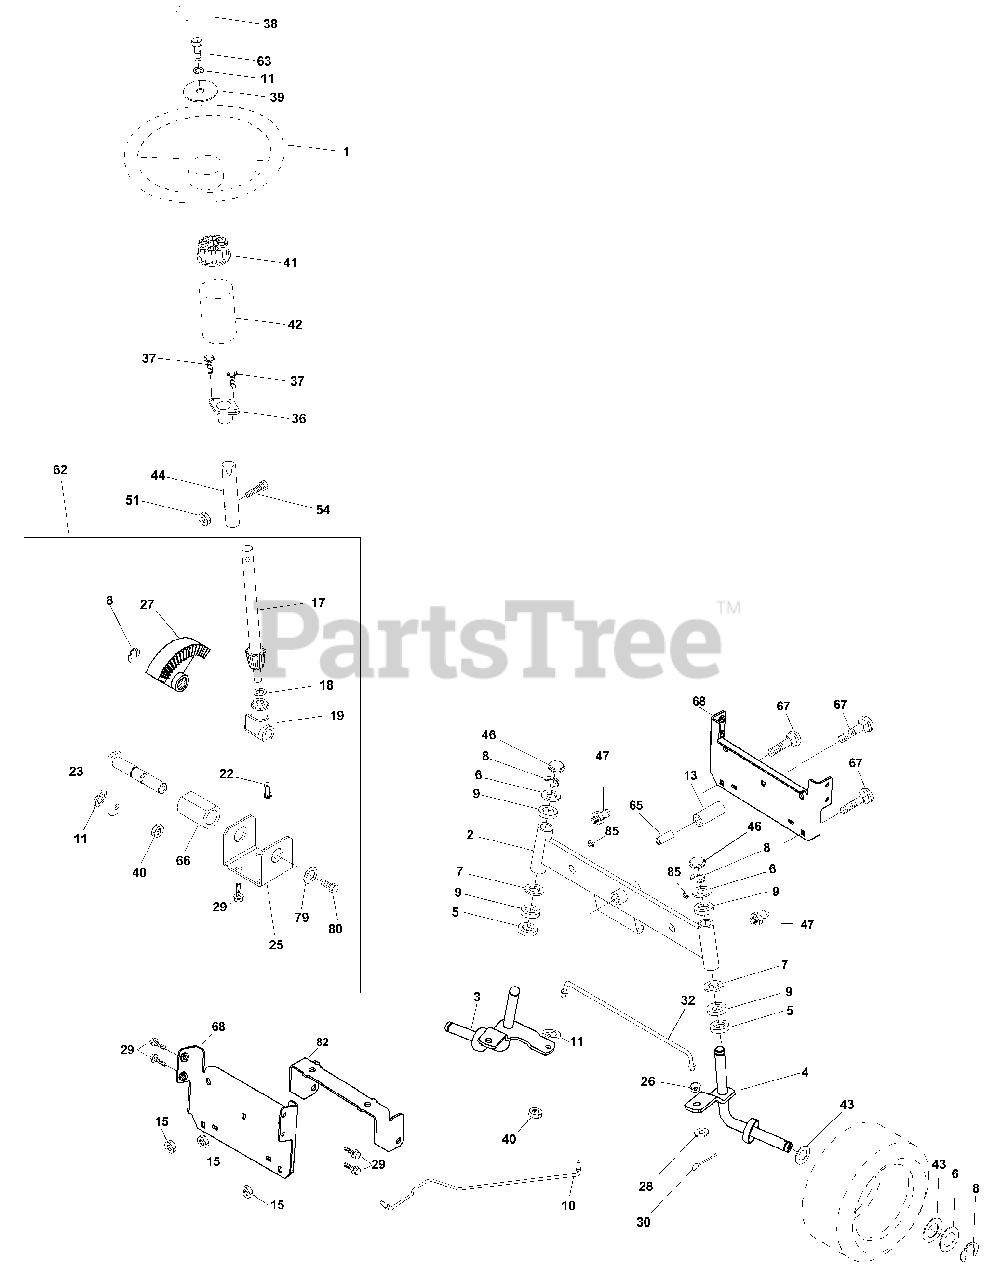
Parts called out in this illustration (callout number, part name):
1	Wheel Steering Ayp/P/L Blk
2	Axle Asm
3	Spindle Asm LH
4	Spindle Asm RH
5	Bearing Race Thrust Harden
6	Washer 25/32 X 1-5/8 X 16 Ga
7	Washer 27/32 X 1-1/4 X 16 Ga
8	Ring Klip #t5304-75
9	Bearing Col Strg Blk
10	Link Drag
11	Washer Lock Hvy Hlcl Spr 3/8
13	Spacer earing Axle Front
15	Hexflange Lock
17	Shaft Asm Strg
18	Washer Thrust 515 x 750 x 033
19	Support Shaft
22	Screw Hex Wsh Hd Torx
23	Shaft Asm Pittman
25	Bracket Steering
26	Bushing Link Drag Blk LR
27	Gear Sector
28	Washer 13/32 X 7/8 X 16 Ga
29	Screw 3/8-16 x 3/4
30	Pin Cotter 1/8 X 3/4 Cad
32	Rod Tie Wire Form 19 75 Mech
36	Bushing Strg 5/8 Id Dash
37	Screw
38	Cap Wheel Steer Ayp
39	Washer 13/32 x 2-3/8 x 12 Ga.
40	Nut Lock Center 3/8-24un
41	Adaptor Wheel Strg
42	Boot Dash Mtl Steering Blk
43	Washer 25/32 X 1 1/4 X 16 Ga
44	Extension Steering
46	Cap Spindle Fr Top Blk
47	Fitting Grease
51	Nut Lock Hex W/Ins 5/16-18
54	Bolt Fin Hex 3/8-16 unc x 1-1/4
62	Kit Steering Assembly Service
63	Bolt Fin Hex 3/8-16 unc x 1 Gr.5
65	Spacer Brace Axle
66	Bearing Arm Pittman
67	Bolt Fin Hex 5/8-11 unc x 2-3/4
68	Brace Axle
79	Washer 13/32 x 1 1/4 x 12 Ga.
80	Bolt Hex 3/8-16 x 3/4
82	Bracket Susp Chassis Front
85	Fastener Christmas Tree
